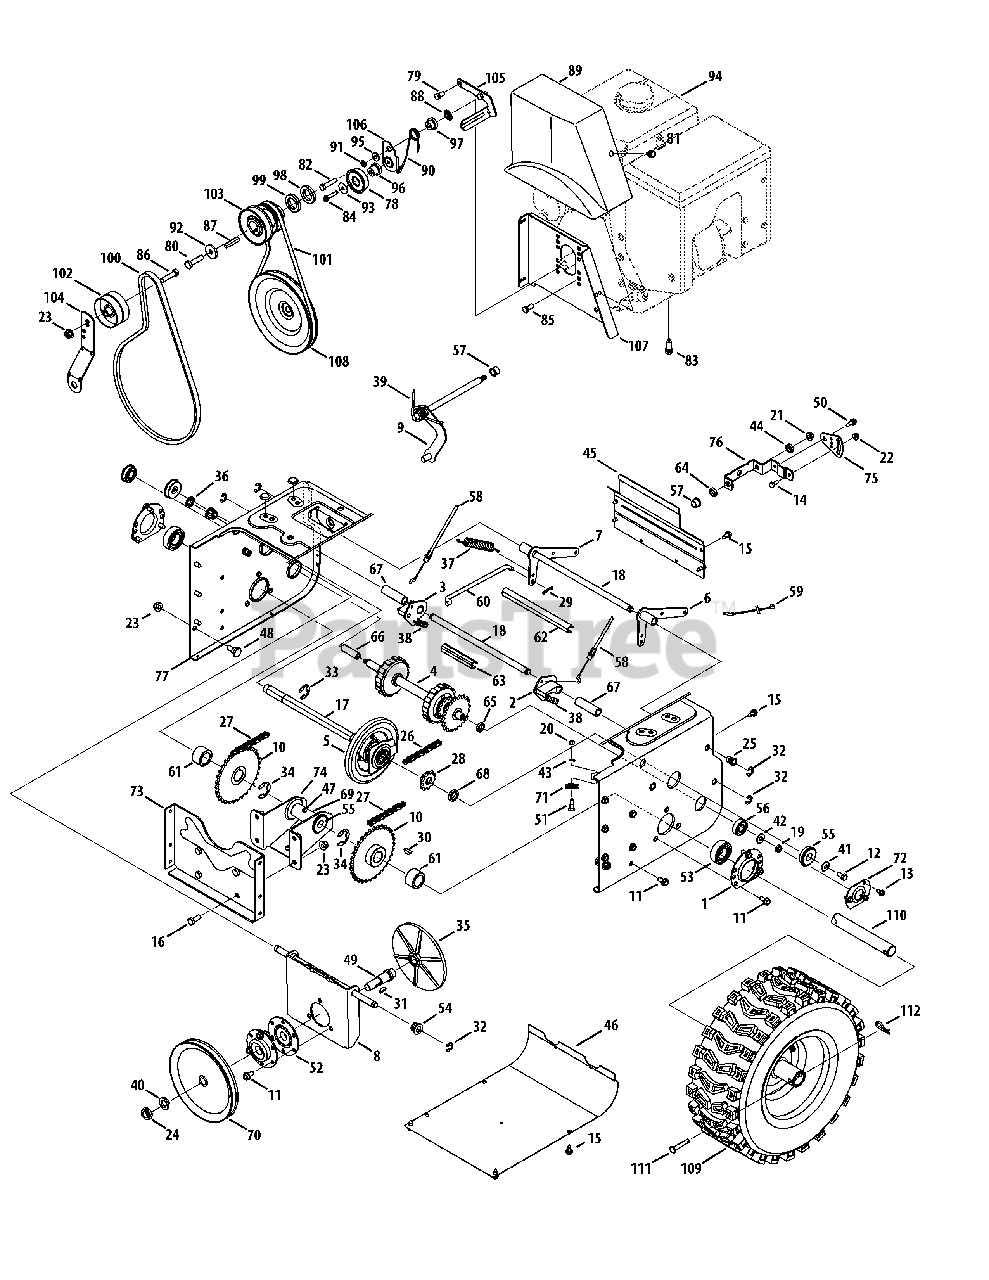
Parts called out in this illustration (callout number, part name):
1	Housing, Bearing
2	Dogg, Steering Drive, LH
3	Dogg, Steering Drive, RH
4	Shaft Assembly, Steering
5	Assembly, Friction Wheel
5	Wheel, Friction, Bonded
5	Screw, Hex Wash
6	Bracket, Auger Actuator
7	Bracket, Drive Actuator
8	Brkt, Friction Drive Suprt.
9	Rod Assembly, Shift
10	Sprocket, 32T
11	TT Screw, 5/16-18 x .750
12	Screw, Hex Cap Lock,
13	Hex Screw, 1/4-20 x .50
14	Hex Head Screw, 1/4-20
15	Screw, Hex Wash.
16	Screw, Hex Cap, 3/8-16
17	Shaft, Hex Drive
18	Shaft, Actuator
19	Nut, Hex Insert Jam Lock
20	Nut, Hex, 1/4-28 GR5
21	Flange Lock Nut, 5/16-18
22	Flange Lock Nut, 1/4-20
23	Flange Lock Nut, 3/8-16
24	Hex Nut, 5/8-18
25	Nut, Insert 3/8-16
26	Chain, Endless, #41 x 36L
27	Chain, #420 x 40L
28	Sprocket, #41 x 10T
29	Pin, Internal Cotter
30	Key, Woodruff
31	Key, Hi-Pro, 3/16 x 5/8
32	E-Ring
33	Ring, Retaining
34	Ring, Retainer
35	Plate, Drive
36	Speed Nut, .500
37	Spring, Extension
38	Spring, Extension
39	Torsion Spring, .750 I.D. x .968 Lg.
40	Washer, Lock, 5/8
41	Wsh, Bell., .34 x .872 x .06
42	Wash, .375 x .812 x .060
43	Washer, Lock, 1/4
44	Flat Washer, .469 x .875 x .105
45	Cover, Upper Frame
46	Cover, Lower Frame
47	Fitting, Lube, 3/16 Drive
48	Screw, Shldr., .498 x .34
49	Spindle, Drive Plate
50	Shoulder Screw, .368 x .113, 1/4-20
51	Screw, Hex Shldr., 1/4-28
52	Ass’y, Bearing/Housing
53	Bearing, Self Aligning
54	Bearing, Hex Flange
55	Bearing, Ball
56	Bush, Flg, .5625 x 1.375 x .4375
57	Bush, Flg, .5 ID x .627 OD
58	Steering Cable, 35.97" Long
59	Cable, Auger Idler
60	Rod, Drive Clutch
61	Spcr., 1.0 ID x 1.50 OD
62	Spcr., .51 ID x 7.895 Lg.
63	Spcr., .51 ID x 3.66 Lg.
64	Spcr., .5151 ID x .750 OD x .220
65	Spcr., .566 ID x .87 OD x .190
66	Spcr., .566 ID x .87 OD x 1.25
67	Spcr., .514 x .632 x 2.44
68	Spacer, .675 x 1.0 x .23
69	Spcr, .6725 x 1.125 x 2.48
70	Pulley, Auger
71	Roller, Cable
72	Bearing Retaining Bracket
73	Bracket, Frame Support
74	Bracket, Axle Support
75	Speed Selector Pivot Bracket
76	Speed Selector Shift Bracket
77	Transmission Frame
78	Idler Pulley Assembly
79	Screw, Hex Cap, 5/16-24
80	Hex Hd. Screw, 3/8-24 x 1.25 GR8
81	Screw, Hx Wash Hd Tapp
82	Screw, Hex Cap, 5/16-24 x 1.50
83	Screw, 3/8-16 x 1.00
84	Screw, 1/4-20 x 1.25
85	Hex Head Screw, 5/16-24 x .875
86	Hex Head Screw, 3/8-16 x 1.75
87	Square Key, 3/16 x 1.00
88	Nut, Push
89	Cover, Belt
90	Torsion Spring, .850 dia. x .333 lg.
91	Washer, Lock, 5/16
92	Washer, Flat, .406 x 1.25
93	Washer, Flat, .265 x 1.0 x .030
94	Engine Complete
95	Shoulder Spacer, .3175 x .500 x .094
96	Shoulder Spacer, .260 x .785 x .538
97	Shoulder Spacer, .340 x 1.00
98	Spacer, 1.155 ID x 1.78 OD x .150
99	Spacer, 1.004 ID x 1.625 OD x .50
100	V-Belt, 4L x 44.60 Lg.
101	V Belt, 3/8 x 36.68
102	Pulley, Flat Idler, 2.75 OD
103	Double Pulley, 3.25 x 2.75
104	Bracket, Auger Idler
105	Belt Keeper Bracket
106	Idler Drive Wheel Bracket
107	Belt Cover Bracket
108	Pulley, Drive
109	Wheel Ass’y. - LH
109	Wheel Ass’y. - RH
109	Valve
109	Bearing
110	Axle, Wheel, 33"
111	Pin, Clevis
112	Pin, Internal Cotter
